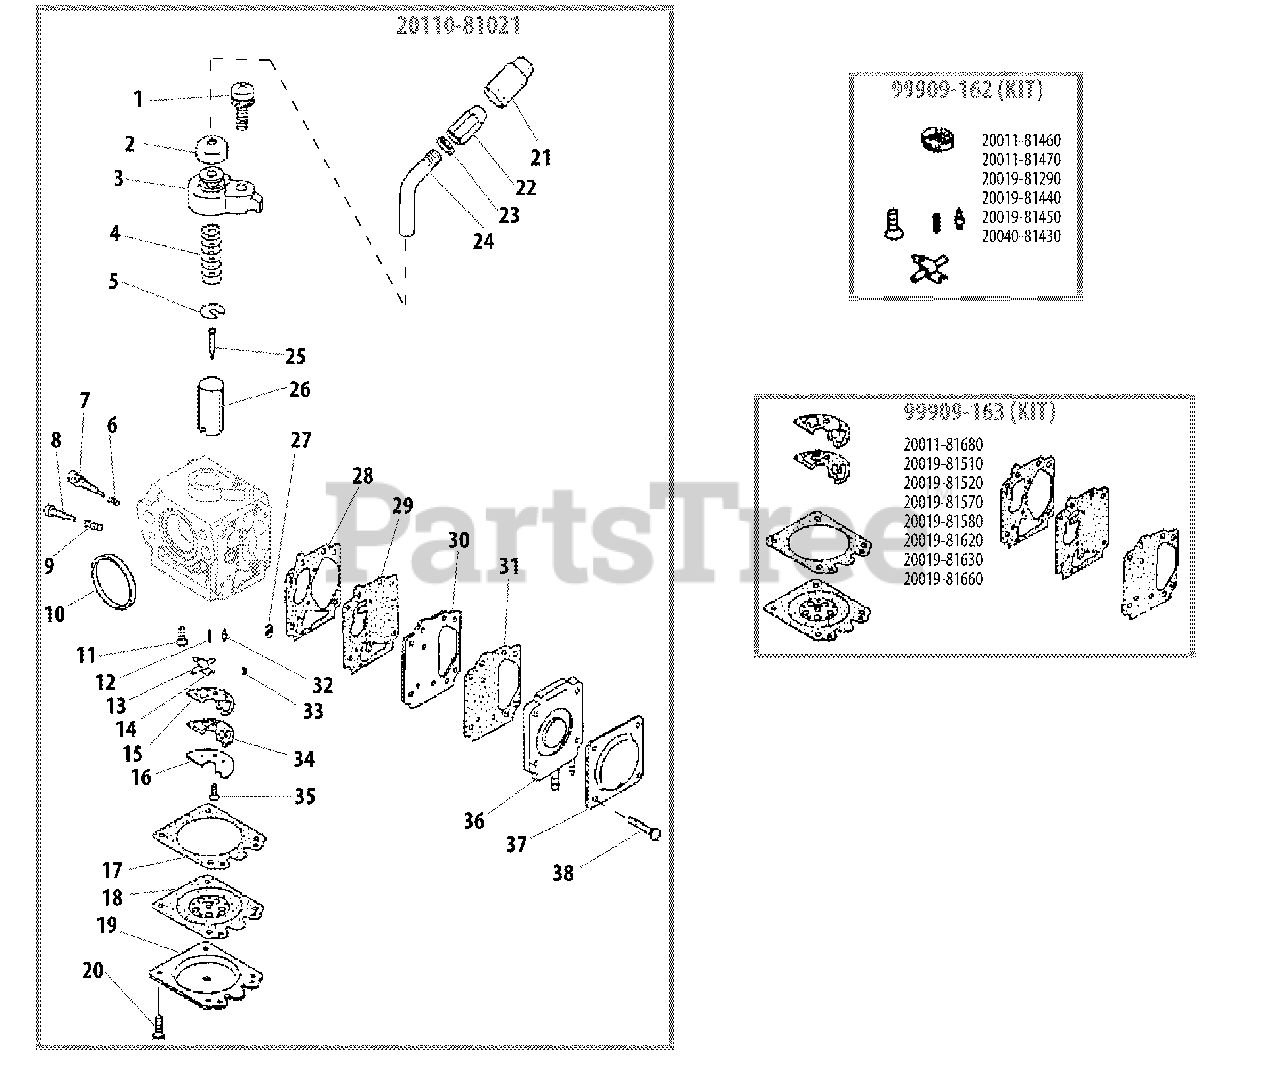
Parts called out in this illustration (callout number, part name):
1	SCREW M5×15
2	CAP, DUST
3	CAP, CARBURETOR
4	SPRING, THROTTLE
5	WASHER, SPRING SUPPORT
6	SPRING
7	SCREW, MAIN ADJUST
8	SCREW, IDLE ADJUST
9	SPRING
10	RING, PACKING
11	SCREW M3×8
12	SPRING
13	PIN, METERING LEVER
14	LEVER, METERING
15	GASKET
16	PLATE
17	GASKET, METERING DIAPHRAGM
18	DIAPHRAGM, METERING
19	COVER, DIAPHRAGM
20	SCREW M3×8
21	CAP, CARBURETOR
22	ADJUSTER, CABLE
23	NUT, LOCK
24	PIPE, CABLE ADJUSTER(4 pieces ×2 M)
26	VALVE, THROTTLE
27	SCREEN, FUEL INLET
28	GASKET, PUMP
29	DIAPHRAGM, FUEL PUMP
30	PLATE, PUMP
31	GASKET, FUEL PUMP
32	VALVE, INLET NEEDLE
33	SPRING, COIL
34	VALVE, CHECK
35	SCREW M3×8
36	COVER, PUMP
37	COVER, DIAPHRAGM
38	SCREW M3×14
A	CARBURETOR
A	REPAIR KIT
A	DIAPHRAGM/GASKET KIT
